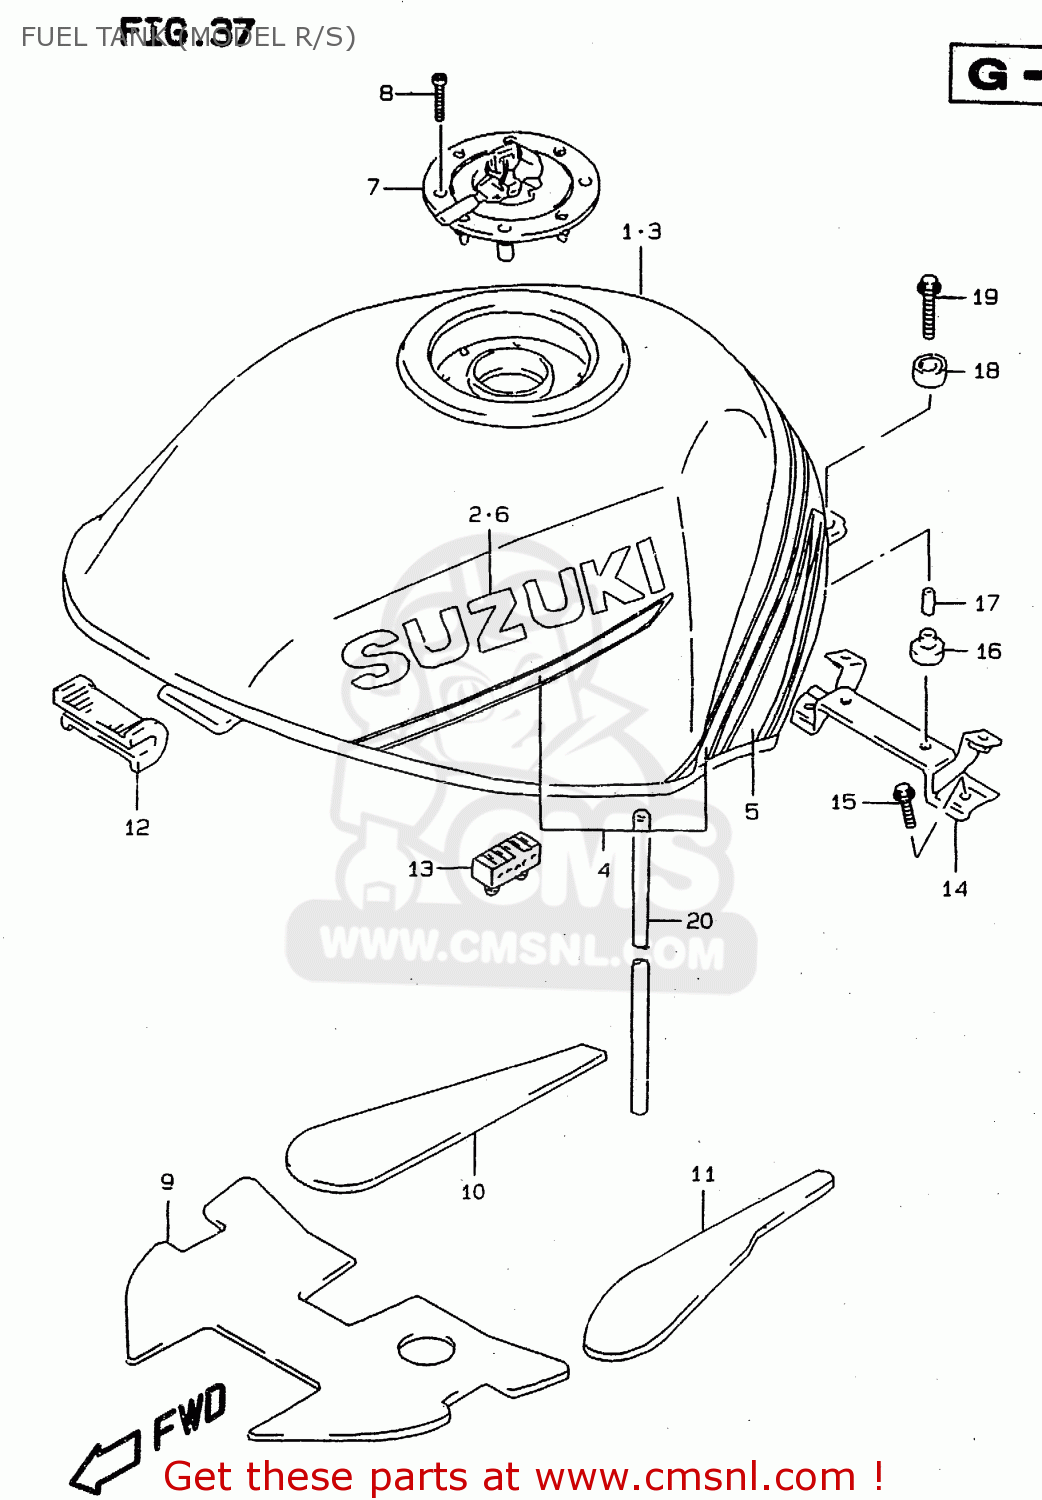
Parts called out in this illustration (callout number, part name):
1	TANK ASSEMBLY,FUEL
2	EMBLEM,FUEL TANK
3	TANK ASSY,FUEL
4	TAPE SET,FUEL TANK
5	TAPE SET,FUEL TANK
6	EMBLEM,FUEL TANK
7	CAP SET,FUEL TANK
8	BOLT(5X20)
9	SHIELD,FUEL TANK HEAT NO.1
10	SHIELD,FUEL TANK HEAT NO.2
11	SHIELD,FUEL TANK HEAT NO.3
12	CUSHION,FUEL TANK FR
13	CUSHION,SEAT(40X20X15)
14	BRACKET,FUEL TANK RR
15	BOLT
16	CUSHION
17	SPACER
18	CUSHION
19	BOLT
20	HOSE(7X10.2X600)
